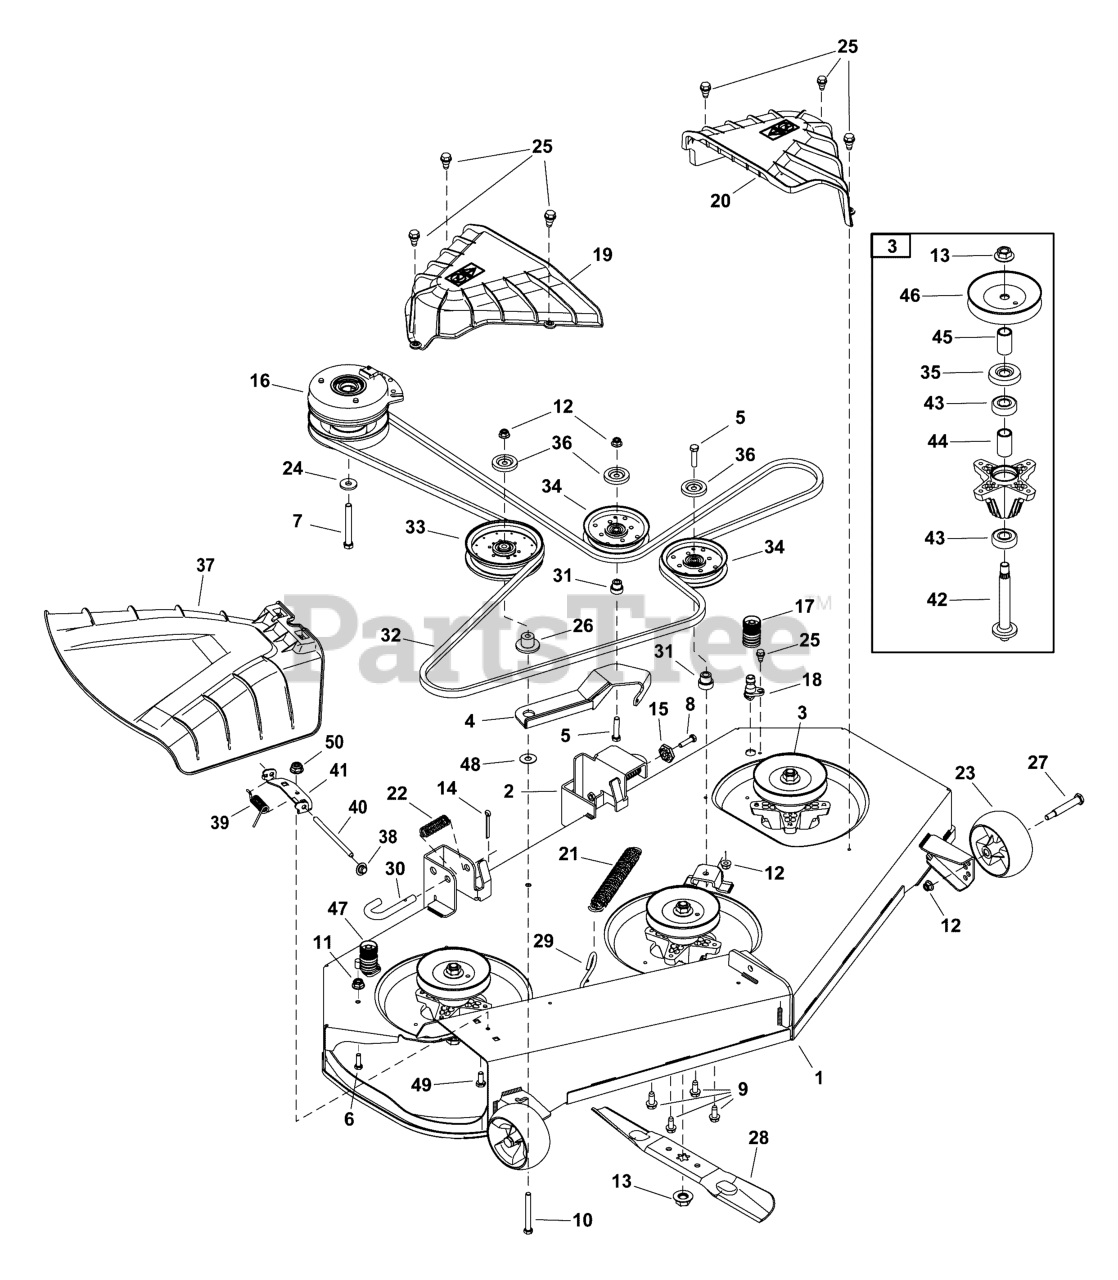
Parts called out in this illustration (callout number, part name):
1	MOWER DECK
2	BRACKET, Deck Lift
3	ASSEMBLY, Spindle
4	ASSEMBLY, Idler Arm
5	SCREW 3/8-16 X 1.75 GR5, Hex
6	SCREW, 5/16-18 X 1.00, Hex Cap
7	SCREW, 7/16-20 X 3.5 GR5
8	SCREW, 3/8-16, Hex Flange
9	SCREW, 5/16-18 X .750, Hex Washer
10	SCREW, 3/8-16 X 3.25 GR8
12	NUT, 3/8-16, Flanged Lock, GR5
13	NUT, 5/8-18 Hex Flange
14	PIN, 5/32 X 1.25, Cotter
15	GEAR, Deck Adjustment
16	CLUTCH, Electric PTO
17	ADAPTER, Water Nozzle
18	NOZZLE, Water
19	COVER, Spindle, RH
20	COVER, Spindle, LH
21	SPRING, 1.25 OD X 1.751, Extension
22	SPRING, .66 X 1.9, Compression
23	WHEEL, 5.0, Deck Ball
24	WASHER, .450 X 1.25 X .164, Flat
25	SCREW, Shoulder, 1/4-20 x 1/2
26	SPACER, Shoulder
27	SCREW, .5 X 2.5 X 3/8-16, Shoulder
28	BLADE, 18.61" (2N1)
29	ROD, Deck Spring
30	ROD, Deck Hangar
31	SPACER, Shoulder
32	V-BELT, B Sec X 148.25 LG
33	PULLEY, 5.00 DIA., Idler
34	PULLEY, 4.50" DIA, Idler
35	SHIELD, Bearing
36	PULLEY CAP, Idler Pulley
37	ASSEMBLY, Chute
38	CAP, Push
39	SPRING, .440 ID X 1.75, Torsion
40	PIN, Hinge
41	BRACKET, Chute, 42”
42	SHAFT, 6.11" LG, Blade Spindle, Star
43	BEARING, Ball
44	SPACER, .792 X 1.060 X 1.860
45	SPACER, .792 X 1.060 X 1.782
46	PULLEY, 5.57" Dia., Spindle
47	CAP, .290 X .500
48	WASHER, 3/8, Flat
49	SCREW, 1/4-20 X .62, Hex Cap
50	NUT, Flange Nylock , 1/4-20
